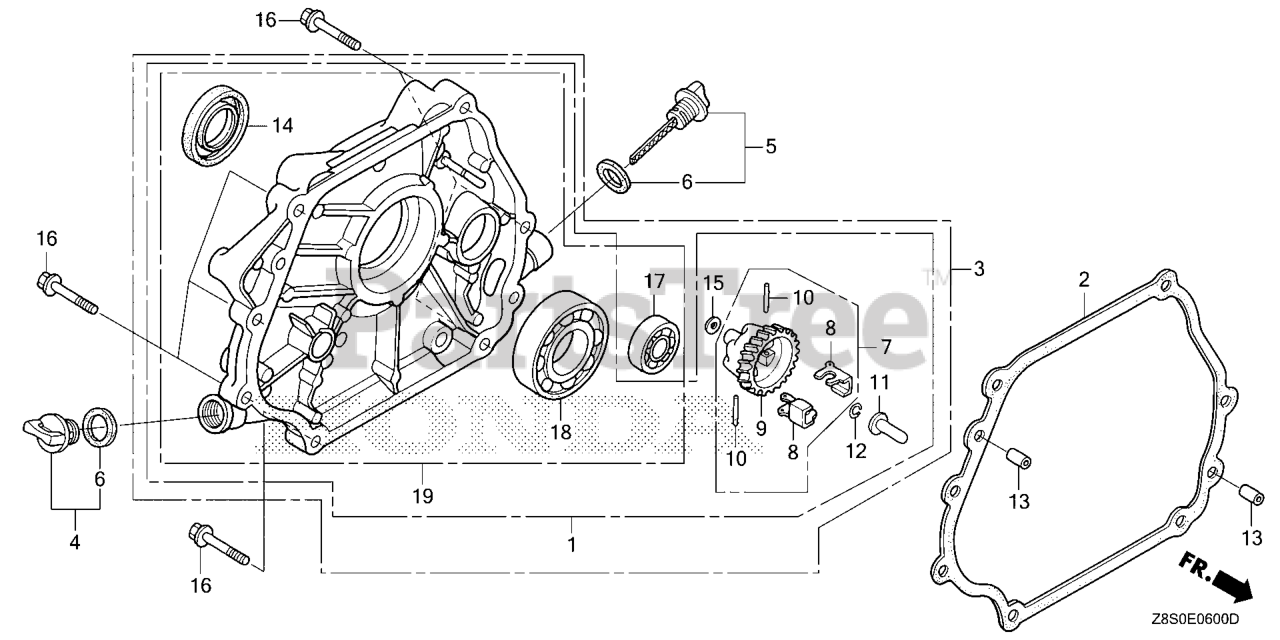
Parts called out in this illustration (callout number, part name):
2	GASKET, CASE COVER
3	COVER ASSY., CRANKCASE
4	CAP ASSY., OIL FILLER
5	CAP ASSY., OIL FILLER
6	GASKET, OIL FILLER CAP
7	GOVERNOR ASSY. (BALANCER)
8	WEIGHT, GOVERNOR
9	HOLDER, GOVERNOR WEIGHT
10	PIN, GOVERNOR WEIGHT
11	SLIDER, GOVERNOR
12	CLIP, GOVERNOR HOLDER
13	PIN, DOWEL (8X12)
14	OIL SEAL (30X46X8) (NOK ASIA)
15	WASHER, PLAIN (6MM)
16	BOLT, FLANGE (8X35)
17	BEARING, RADIAL BALL (6202)
18	BEARING, RADIAL BALL (6206)
